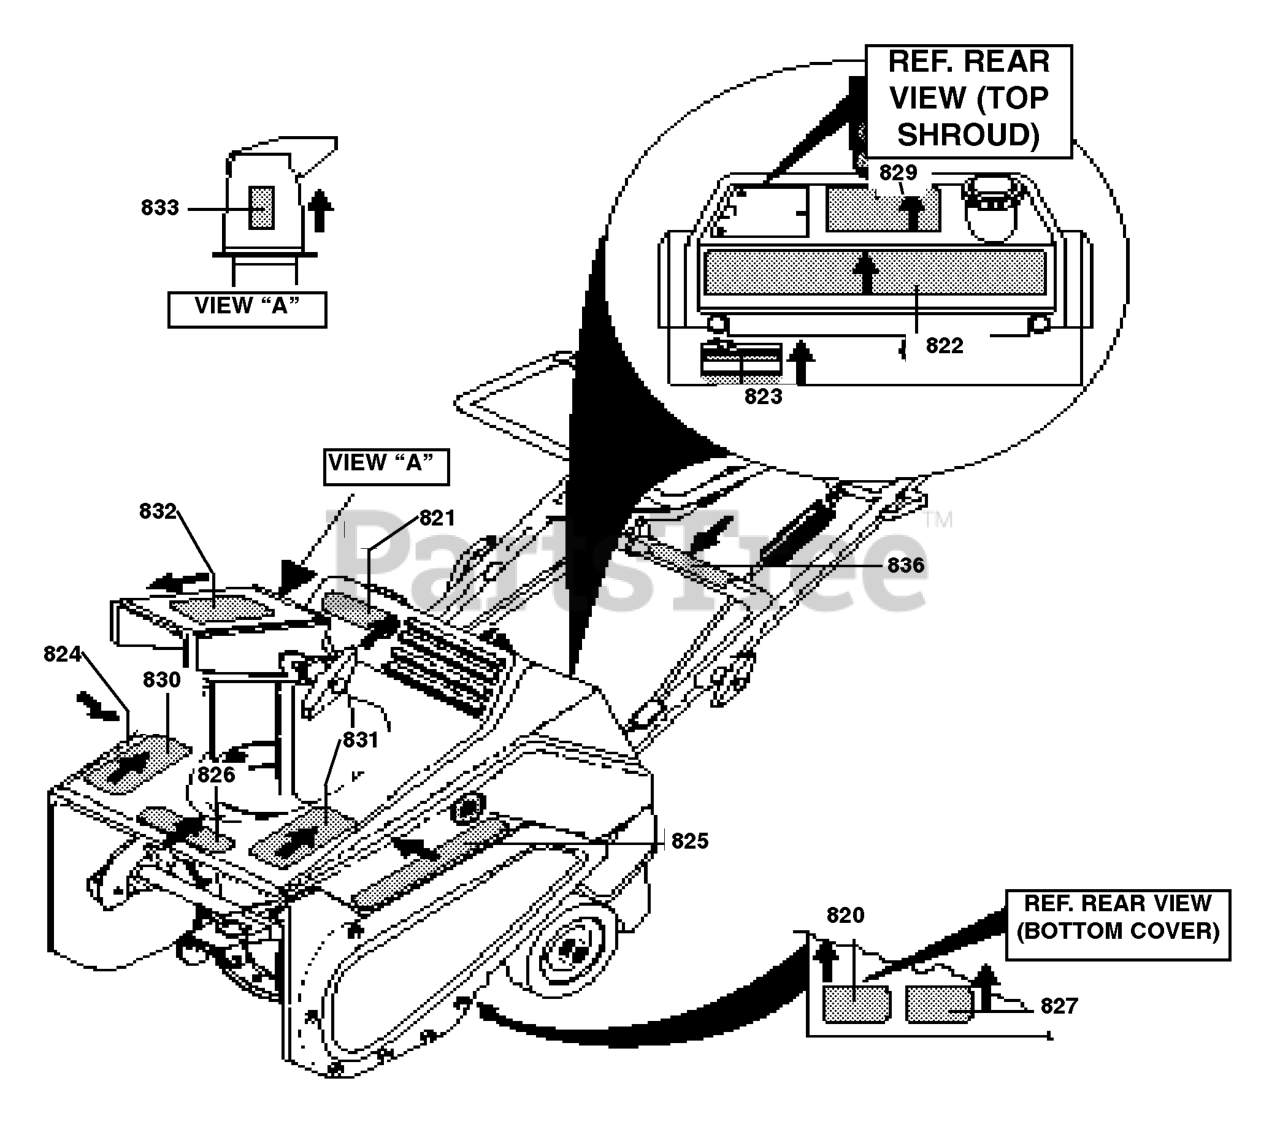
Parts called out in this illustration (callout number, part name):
821	MP BRACKET, WORM ADJ
822	DECAL, CONTROL PANEL
823	DECAL, CHOKE
824	DECAL, ST521E SIDE PANEL RH
825	SPACER, SLEV
826	DECAL, HUSQVARNA TOP COVER
827	DECAL, EPA
829	DECAL, START INSTR
830	DANGER CHUTE DECAL
831	DECAL-DANGER AUGER/FOOT
832	DECAL, "CROWN" UPPRE CHT
833	DECAL, DANGER
836	DECAL, AUGER CONTROL BAR
